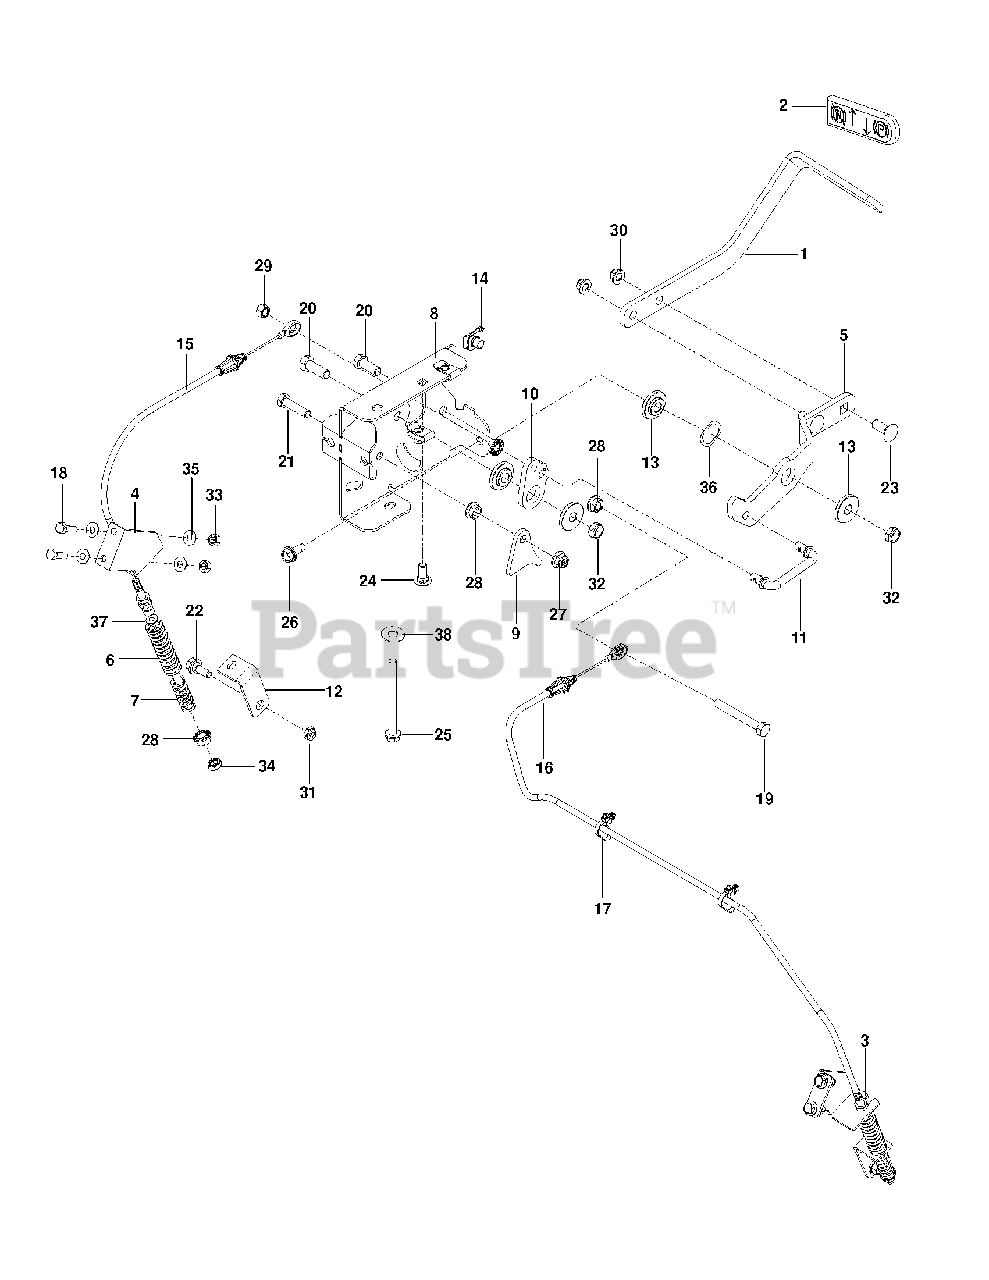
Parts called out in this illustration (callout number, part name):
1	ARM, BRAKE
2	GRIP, PARK BRAKE
3	BRKT, BRAKE RT, BLK
4	BRKT, BRAKE LT, BLK
5	LEVER, BRAKE
6	SPRING, RETURN
7	SPRING, ENGAGEMENT
8	MOUNT, BRAKE WLDMT
9	ACTUATOR, SWITCH
10	BELLCRANK, BRAKE
11	LINKAGE, BRAKE
12	BRKT, BRAKE, BLK
13	BUSHING, BRAKE
14	U-CLIP 5/16-18 NUT RETAINER
15	RP_CABLE, BRAKE, SHORT
16	RP_CABLE, BRAKE, LONG
17	TIE WRAP, 8-3/8", W/CLIP
18	HCS 1/4-20X7/8 GR5
19	HCS 5/16-18 X 2 1/2 TPBLT
20	HCS 3/8-16X1.GRD.5.ZD
21	HCS 5/16C X 1
22	BOLT, SHOULDER
23	RHSNB 3/8C X 1
24	BOLT 5/16C X 3/4" CARRIAGE
25	HHFS 5/16-18 X 3 3/4
26	BOLT 5/16-18 X 3/4
27	5/16-18 NYLOC FLANGE NUT
28	NUT 5/16C WHIZ
29	NUT 5/16 NYLOC
30	NUT 3/8-16 HEX FLG NYLOC ZD
31	5/16-18 THIN PROF NY
32	NUT HEX 3/8-16 NYLON, THIN
33	RP_NUT 1/4-20 NYLOC
34	NUT 5/16-18 HEX JAM ZD
35	WASHER 1/4 SAE
36	WASHER, .825 X 1.087, WAVE
37	WASHER 3/8 SAE FLAT
38	WASH USS FLAT 1/2
